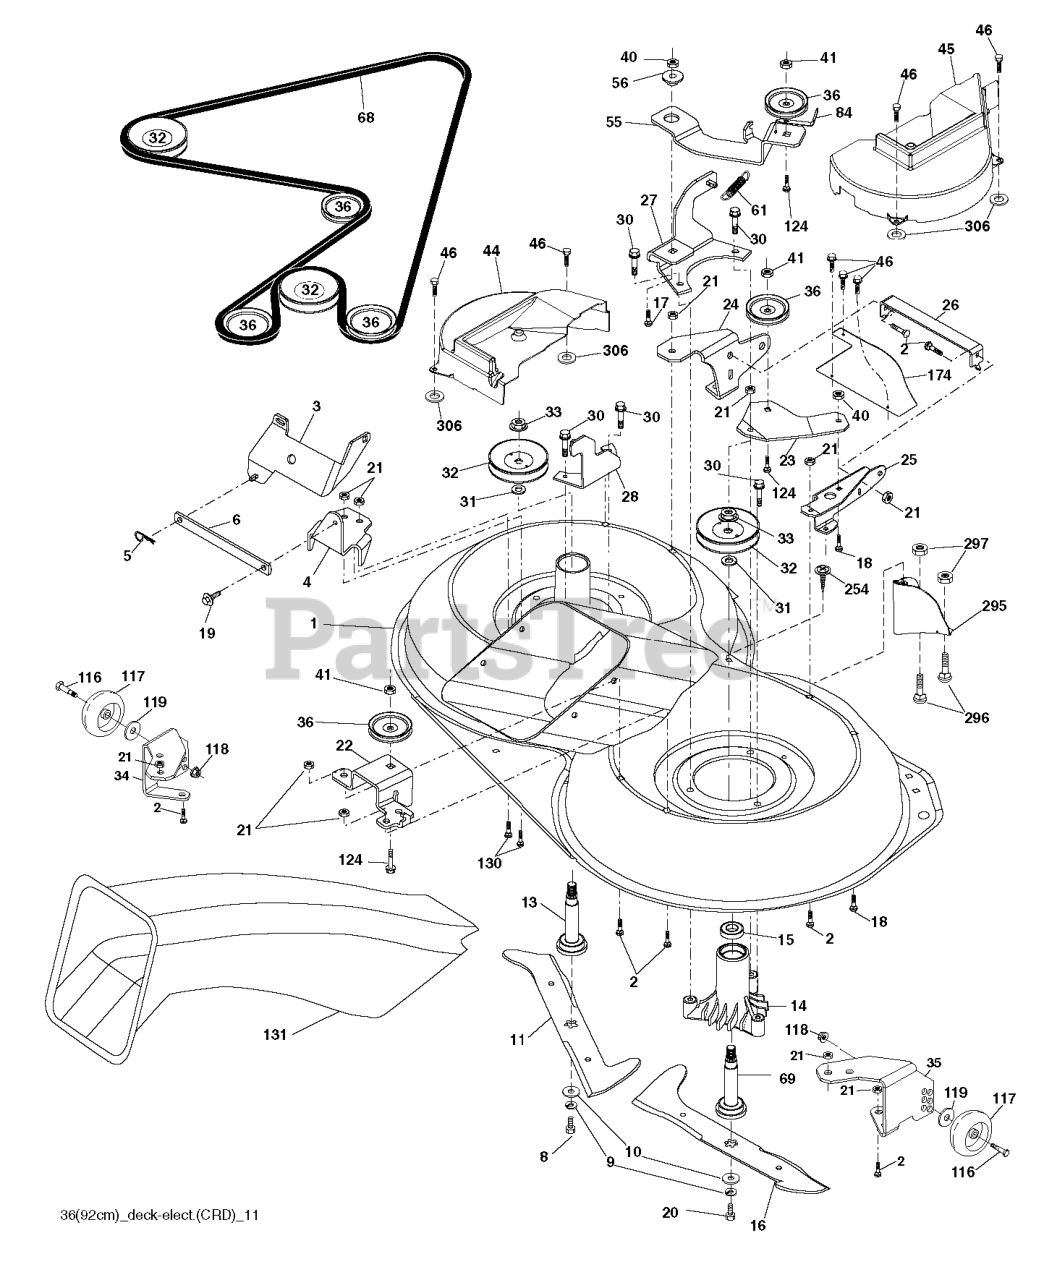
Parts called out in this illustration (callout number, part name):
2	RP BOLT 5/16-18 X3/4 ZN/YEL GR
5	RETAINER-SPRNG RB
6	BAR.SWAY.92.CRD
8	BOLT.3/8-24X1.25 GR8
9	LOCKWASHER
10	WASHER.BLADE
13	SHAFT ASM VENT
14	HOUSING.MANDREL.VENTED (MACHD)
17	BOLT.3/8-14X1.25
19	BOLT SHD 5/16-18
20	BOLT.3/8-24X1.25GR8. LHTHRD
21	LOCKNUT
26	SUPPORT
30	SCREW, WASHER HEAD
31	WASHER.SPACER.MANDREL
32	PULLEY MANDREL
33	NUT.FLANGE.LOCK.TOP
36	PULLEY.IDLER.4.25
41	NUT LOCK FLG 3/8-16 UNC
46	SCREW.1/4-20X5/8
55	ARM.IDLER.92 CRD.2006
56	SPACER.RETAINER.MOWER
61	SPRING
68	BELT.DRIVE.92CM.CRD.2006
69	SHAFT.ASM.W/LWR.BRG.RH.THREAD
84	KEEPER, BELT IDLER
116	BOLT.SHOULDER.3/8-16X3-5/8.
117	RP WHEEL. GUAGE RALLY
118	NUT LOCK FLG 3/8-16 UNC
119	WASHER
124	BOLT.3/8-16X1.50
130	BOLT.CARR.SQNK.5/16-18UNC.X3/4
131	CHUTE BAGGER
254	SCREW 3/8-16X1
296	BOLT
297	NUT CENTERLOCK
306	PALNUT 1/4
